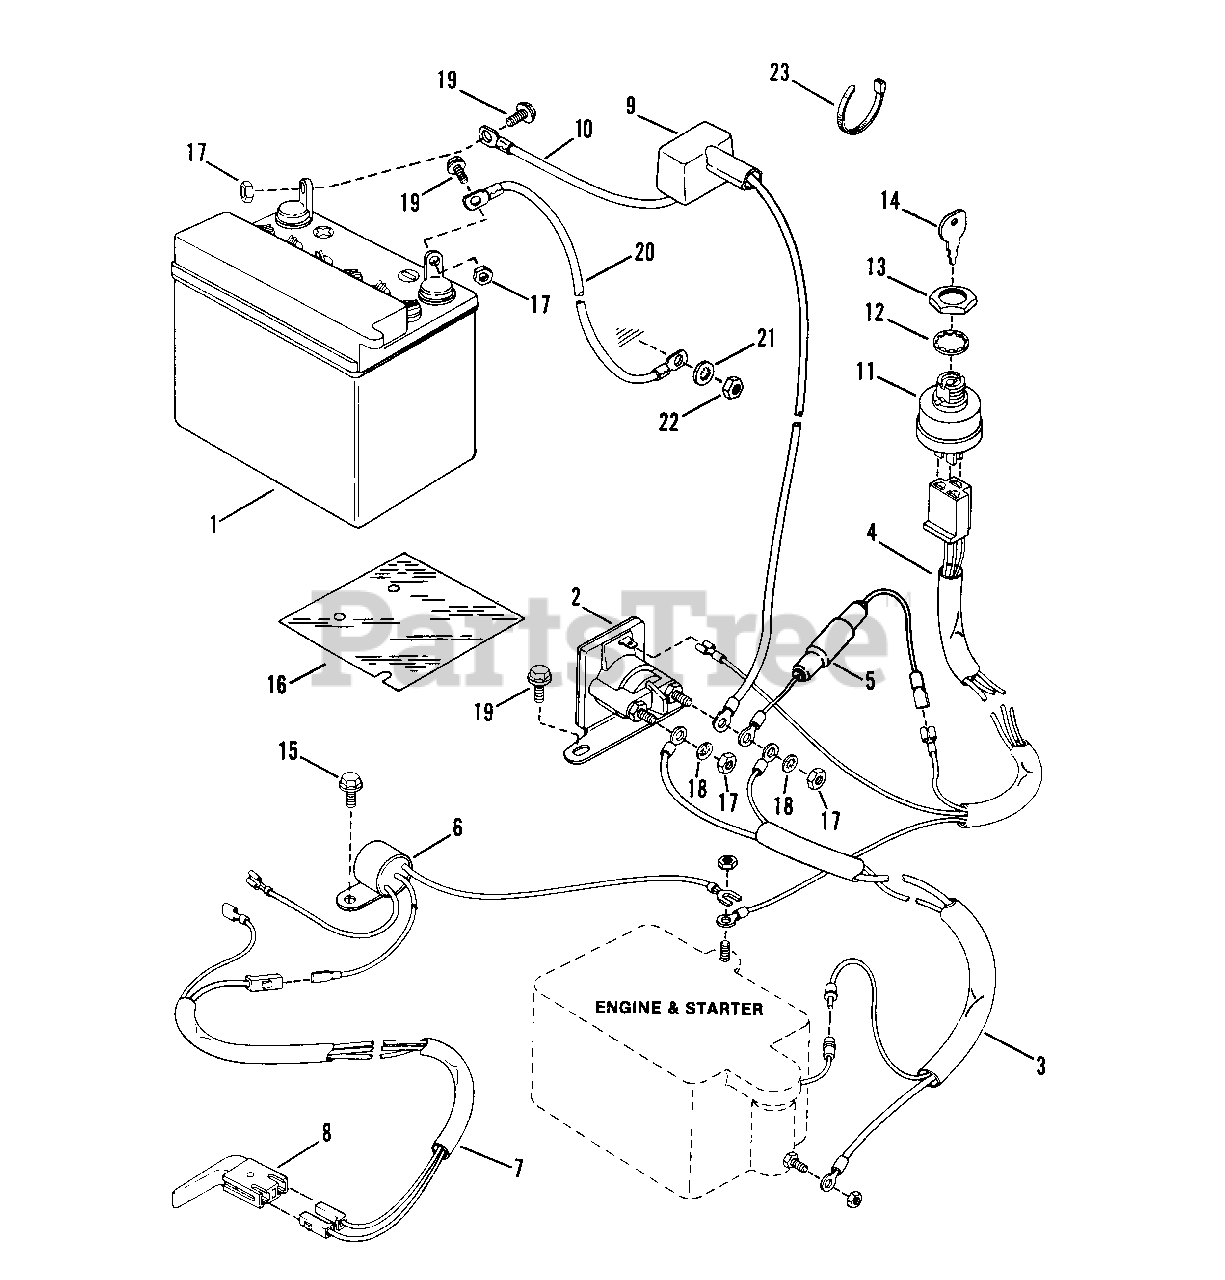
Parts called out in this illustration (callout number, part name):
1	KIT, 12V Dry Charge Battery
2	SOLENOID
3	HARNESS, Starter Wiring
4	HARNESS, Ignition Wiring
5	HOLDER, Fuse
6	INTERLOCK
7	HARNESS, Deck Interlock Wiring
8	SWITCH, Deck Interlock
9	COVER, Battery Cable
10	CABLE, Positive (Red)
11	SWITCH, Ignition
12	WASHER, 5/8 Internal Tooth Lock
13	NUT, 5/8-32 Hex
14	KEY, Switch (With Cover)
15	SCREW, 1/4-20 x 1/2" Self-Tapping
16	PROTECTOR, Solenoid
17	NUT, 1/4-20 Hex
18	WASHER, 1/4 Internal Tooth Lock
19	SCREW, 1/4-20 x 5/8" Hex Head Cap
20	CABLE, Negative
21	WASHER, 5/16 Internal Tooth Lock
22	NUT, 5/16-18 Hex
23	TIE, Cable
